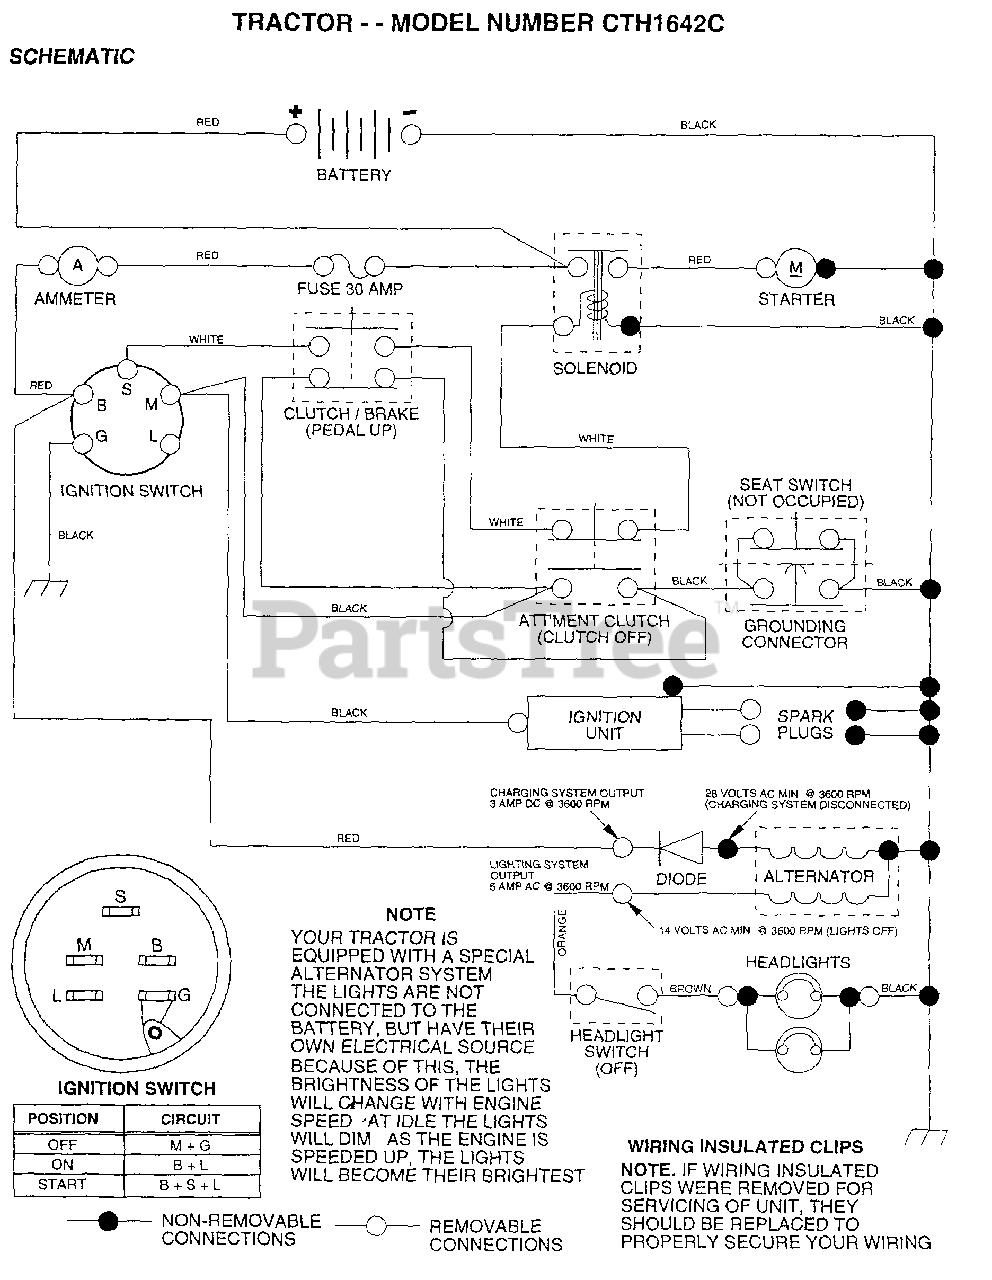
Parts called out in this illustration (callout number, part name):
1	DECAL.FEND.RALLY
1	VALVE CAP
2	VALVE STEM LT
3	DECAL HOOD LH
4	DECAL.HOOD.RH
4	TUBE.5.3/4.5/6
5	DECAL.CHAS.42.HYD
5	RIM.FRONT.6.YELLO
6	DECAL.GRILLE.RLY
6	FITTING LT
7	DECAL
7	"FLANGE, BEARING"
10	DECAL BRAK PARK
10	TUBE.18X9.5-8
11	DECAL
11	HUB CAP
12	DECAL.DASH.INST.
13	DECAL.WHL.STR.RLY
14	DECAL.BTRY.DANGER
15	REFLECTOR-TAIL YT
16	FOOTREST PAD
17	DECAL, HP ENGINE
18	DECAL SADLE HYDRO
